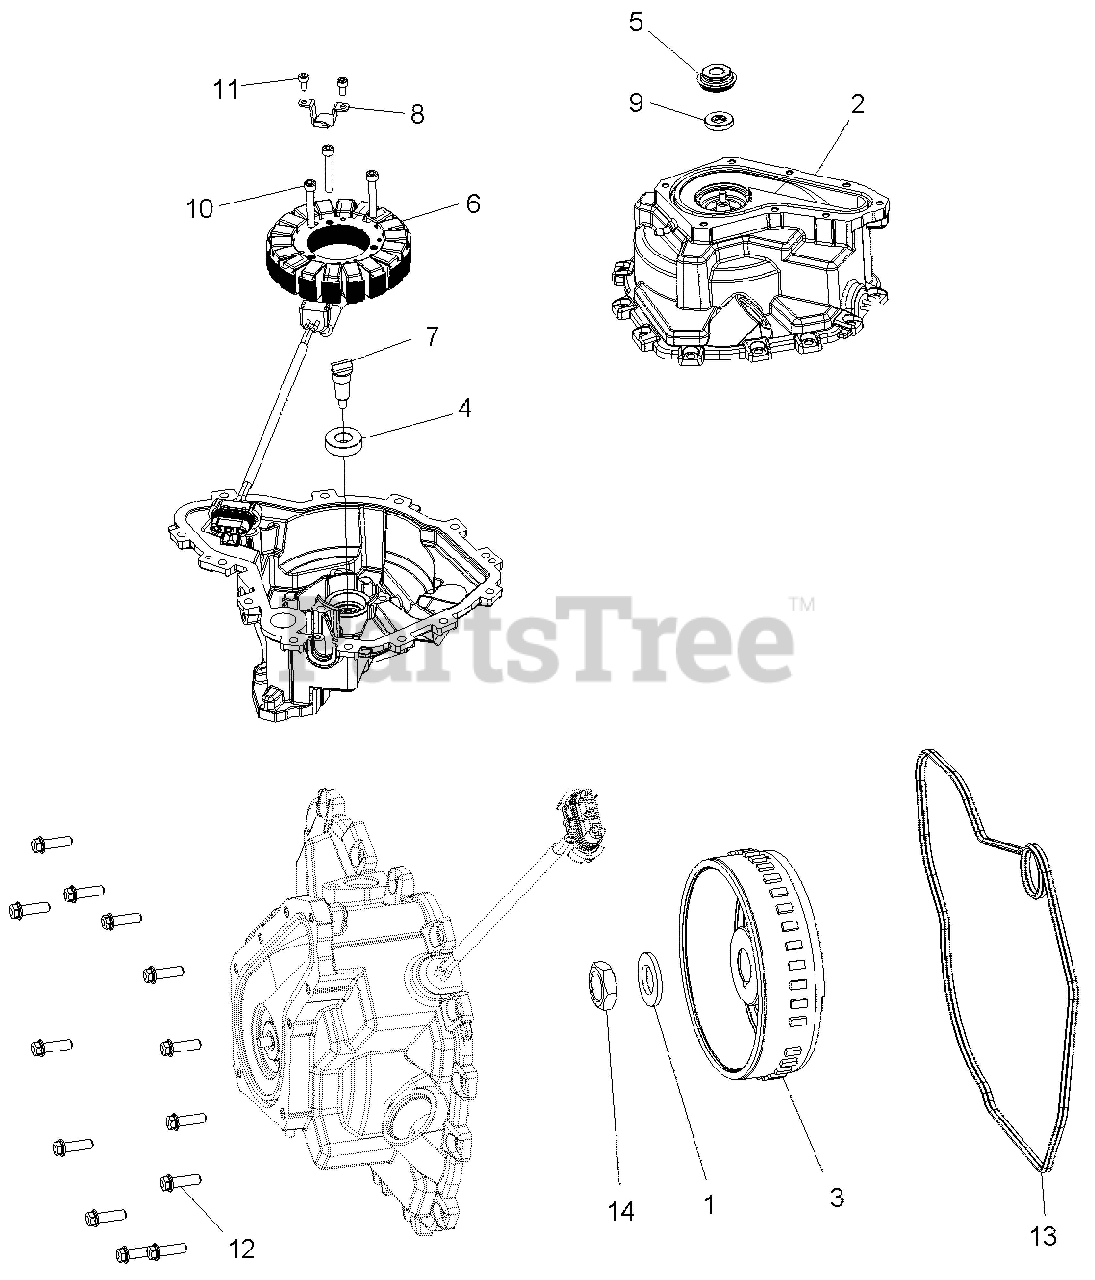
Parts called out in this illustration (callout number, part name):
2	KIT-IGNITION
3	FLYWHEEL
4	BEARING-SHAFT,WATERPUMP
5	SEAL-WATERPUMP SHAFT,WATER
6	STATOR-660W
7	SHAFT-PUMP DRIVE,G-1CYL
8	GUIDE-STATOR LEAD
9	SEAL,TYPE S,ARS
10	SCR-M6X1.0X40,HX/SOC/CP-Y/D
11	SCR-M5X0.8X10 SOC/CP-D
12	SCR-M6X20,HXFLG,0600214
13	GASKET-STATOR COVER
14	NUT-HEX,M18X1.5 4 JAM,RH
